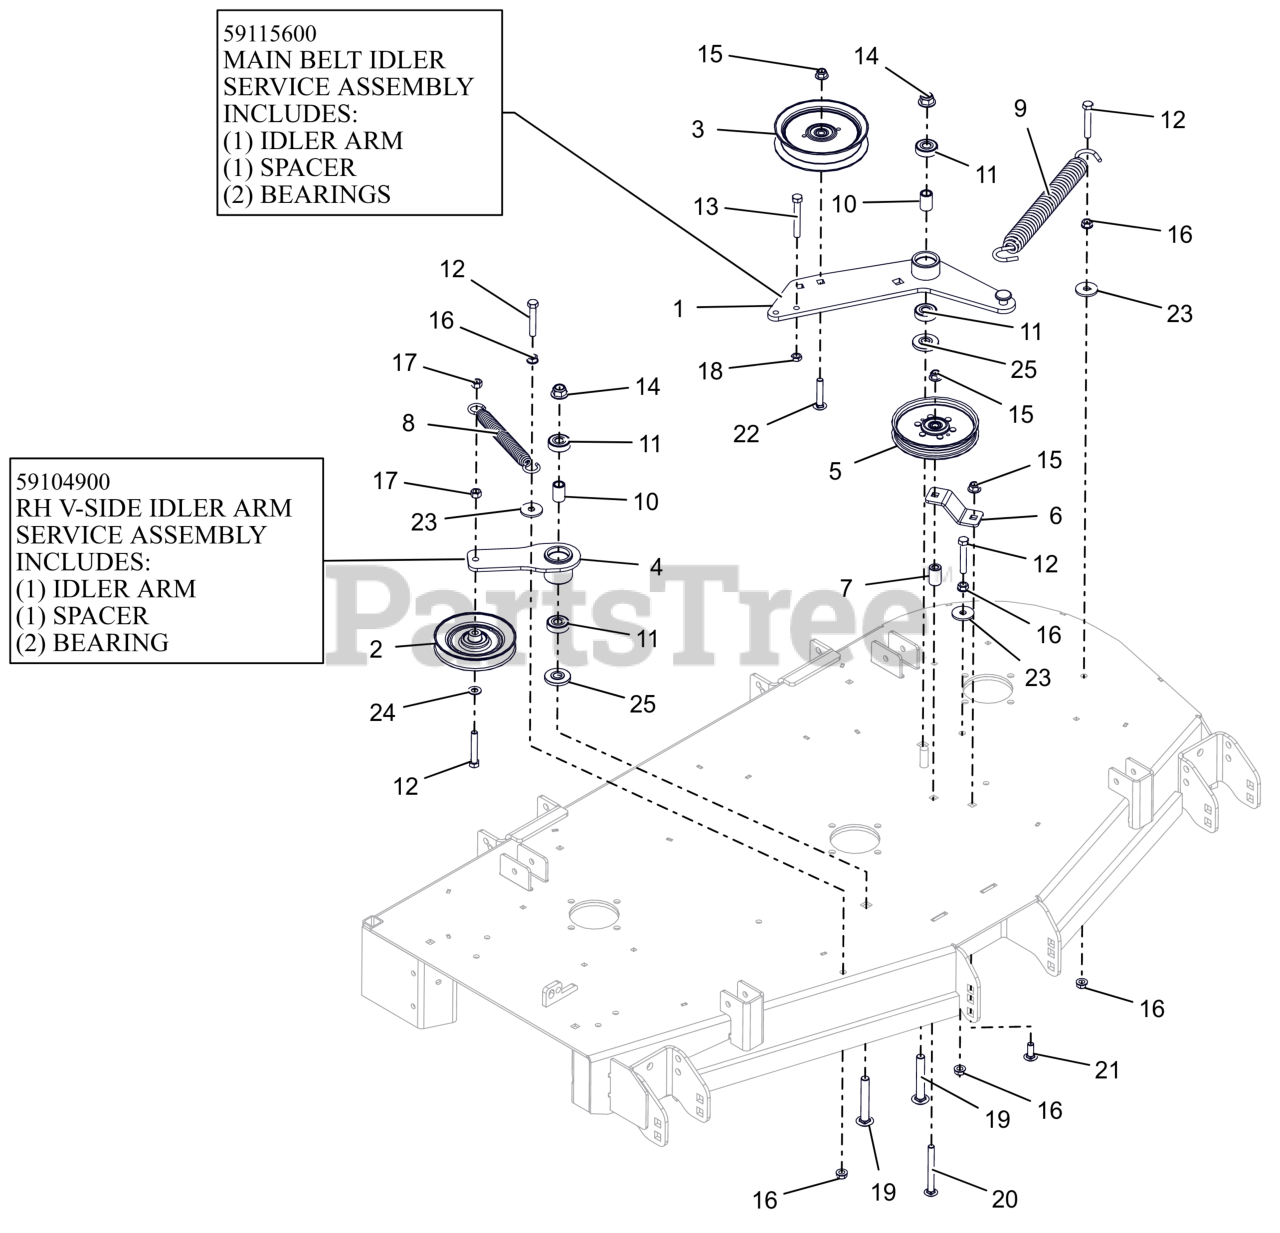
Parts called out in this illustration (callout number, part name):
1	WLDMT, DECK PTO IDLR ARM
1	ASSEMBLY, MAIN BELT IDLER
2	IDLER, V-5.00"
3	IDLER, FLAT 5.00"
4	WLDMT, DECK RH IDLER ARM
4	RH V-SIDE IDLER ARM ASSEMBLY
5	PULLEY, FLAT IDLER
6	PTO FIXED IDLER MTG BRKT -RED
7	BUSHING, SLV .380X.750X1.190
8	SPRING, EXTENSION
9	SPRING, EXTENSION
10	SPACER .510 X .75 X 1.1485
11	BRG-BALL .500X1.38X.437
12	BLT,HEX .38-16X2.25 G5 ZCC
13	BLT, HEX .38-16X2.75 G5 ZCC
14	NUT,NYL-FLG .50-13 GF ZCC
15	NUT,NYL-FLG .38-16 GF ZCC
16	NUT, SPNLK-FLG .38-16 G5 ZCC
17	NUT-LK-CTR .38-16 ZC120
18	NUT-JAM .375-16 G2 ZCC
19	BTL,RHSSN .500-13 X 3.25 G5 ZCC
20	BLT,RHSSN .38-16X3.50 G5 ZCC
21	BLT,RHSSN .38-16X1.00 G5 ZCC
22	BLT,RHSSN.375-16X2.00 G5 ZCC
23	WSHR,FLT .406X1.375X.135 ZCC
24	WSHR,FLT .406X.812X.065 ZCC
25	SPACER, IDLER ARM
